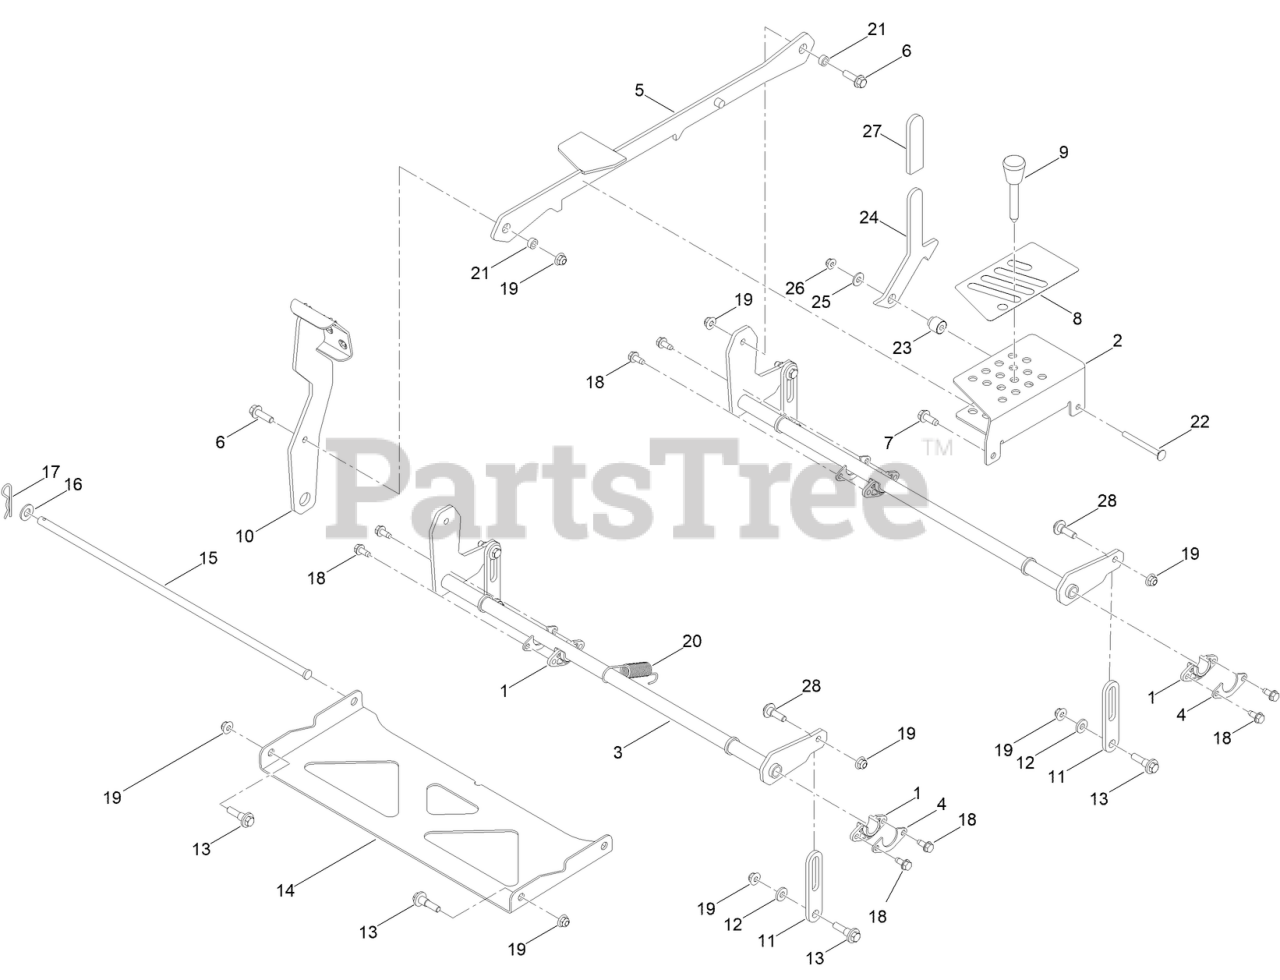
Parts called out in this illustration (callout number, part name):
1	BEARING-FLANGE
2	BRACKET-HOC
4	GUSSET-DECK LIFT
6	SCREW-HHF
7	SCREW-HWH
8	DECAL-HOC
9	HOC PIN ASM
12	SPACER-HUB, BLOWER
13	BOLT-SHOULDER
14	PAN-DECK PIVOT
15	PIN-DECK
16	WASHER-FLAT
17	PIN-HAIR
18	SCREW-HWHTF
19	NUT-HF, NI
20	SPRING-EXTENSION
21	SPACER
22	SCREW-CARR
23	SPACER-STEPPED
24	PLATE-TRANSPORT LOCK
25	WASHER-PLAIN
26	NUT-HF
27	GRIP-HANDLE
28	SCREW-SHOULDER, HWH
